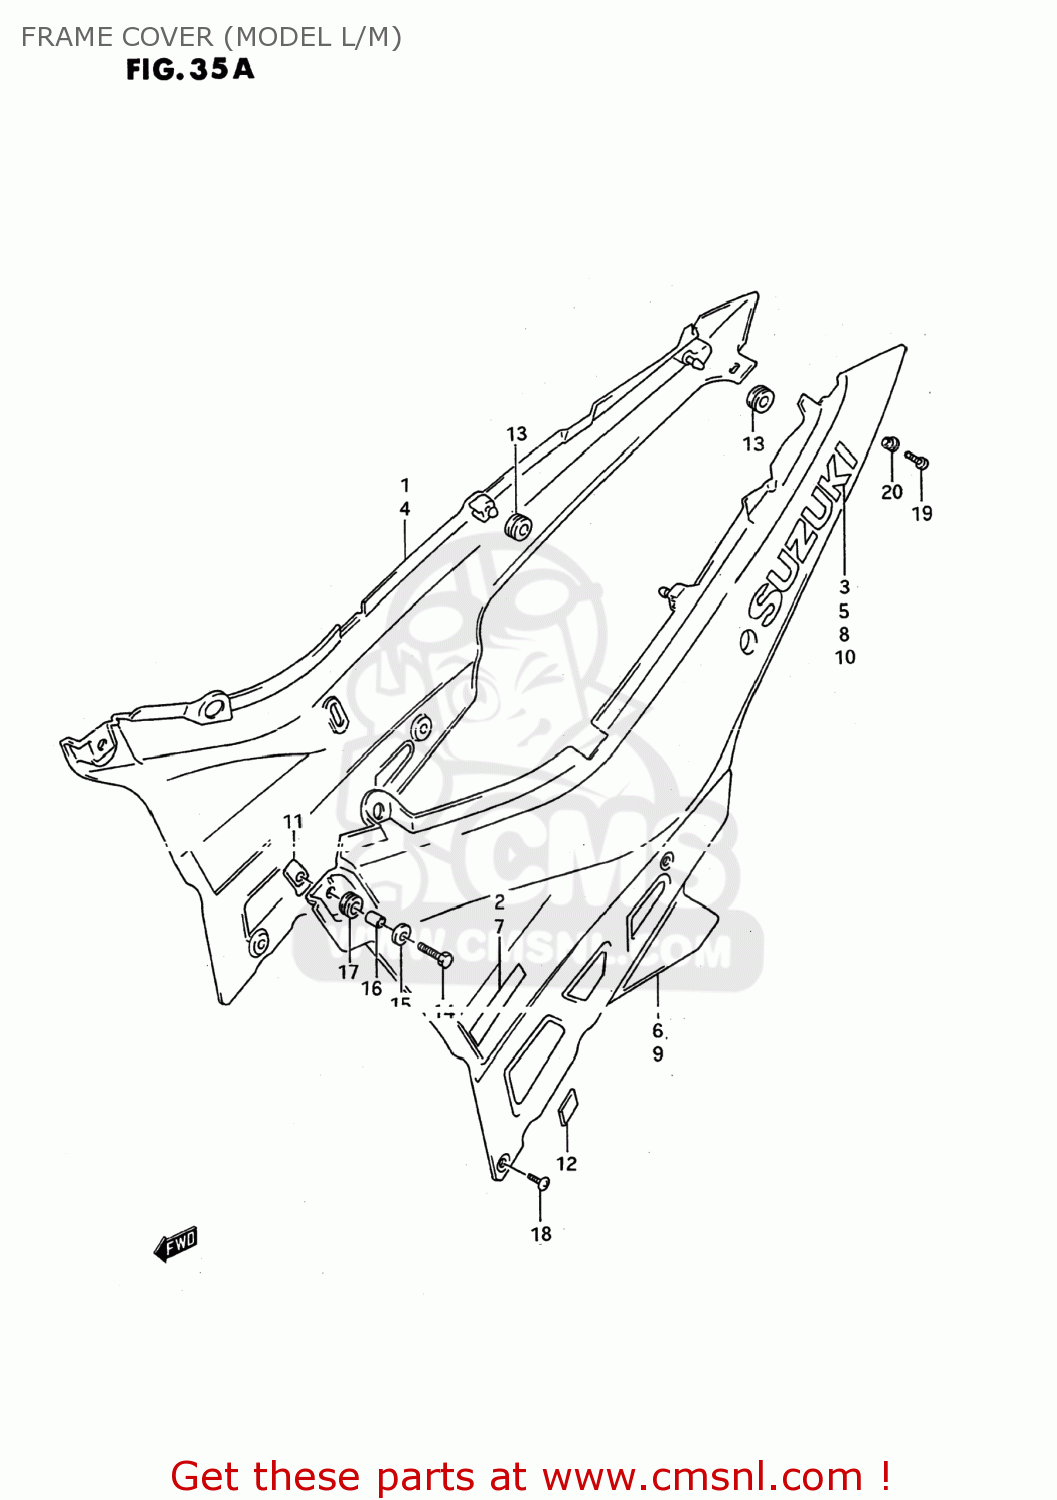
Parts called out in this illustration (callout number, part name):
1	COVER COMP,FRAME,RIGHT
2	TAPE SET,FRAME COVER STRIPE
3	EMBLEM
4	COVER COMP,FRAME,RIGHT
5	EMBLEM,FRAME COVER
6	COVER COMP,FRAME,LEFT
7	TAPE SET,FRAME COVER STRIPE
8	EMBLEM
9	COVER COMP,FRAME,LEFT
10	EMBLEM,FRAME COVER
11	PLATE,FRAME COVER
12	CUSHION,FRAME COVER
13	CUSHION
14	BOLT(6X20)
15	WASHER
16	SPACER (6.1X9X9)
17	CUSHION
18	SCREW(5X15.3)
19	SCREW, FRONT & REAR
20	WASHER
